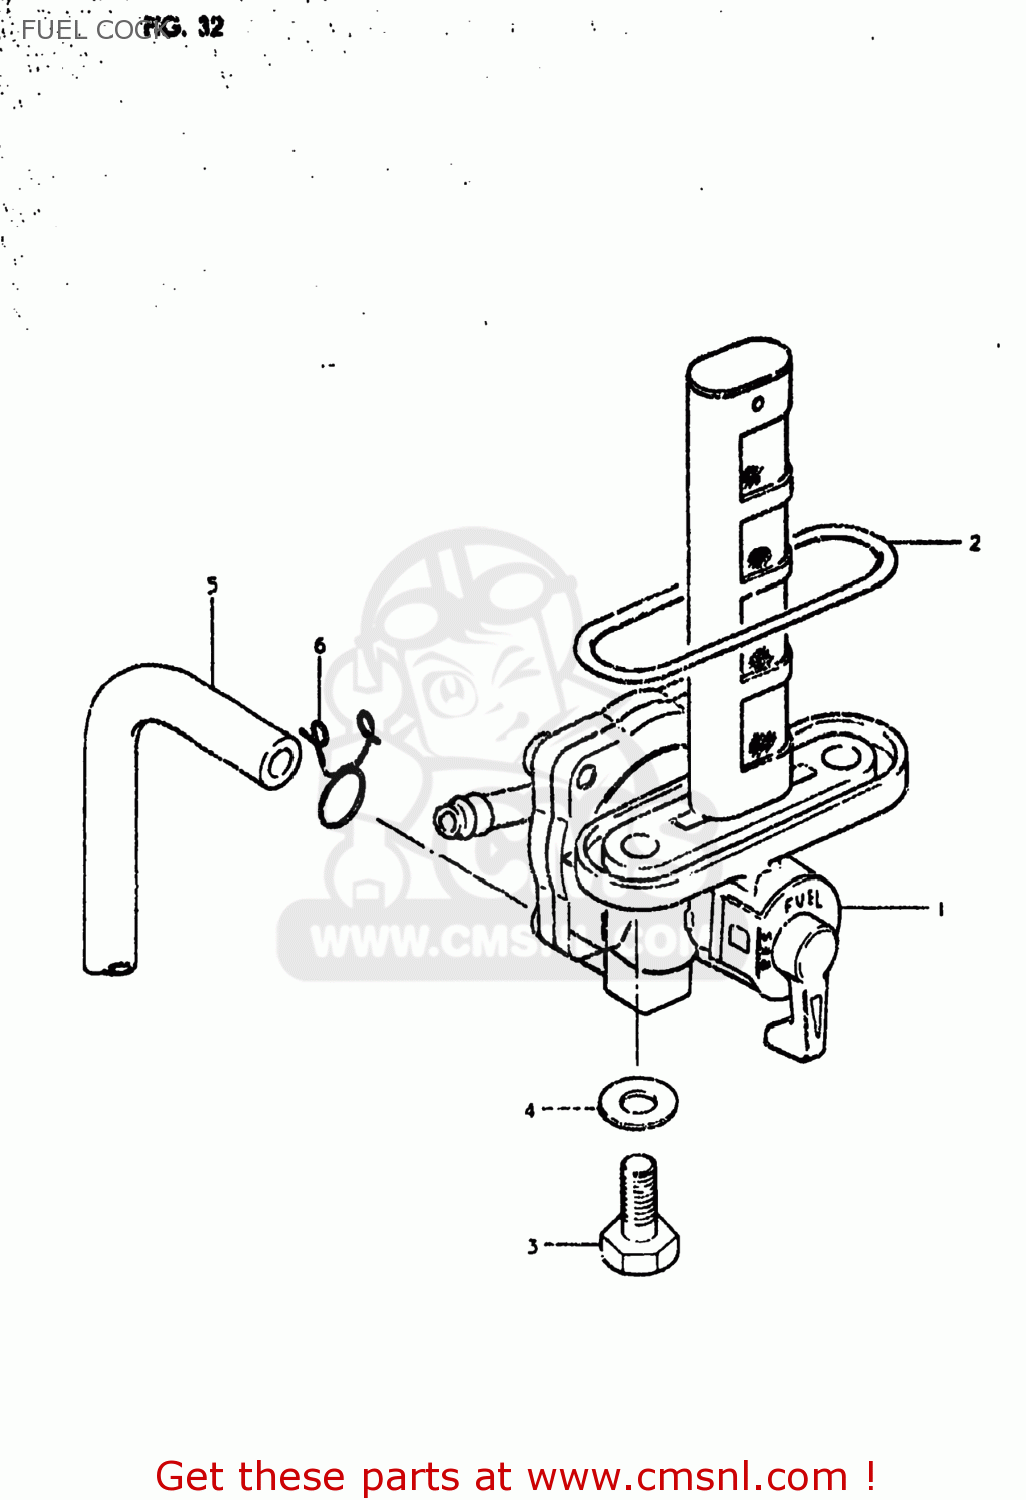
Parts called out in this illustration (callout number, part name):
1	COCK ASSEMBLY,FUEL
2	O RING
3	BOLT(6X20)
4	GASKET
5	HOSE
6	CLIP
